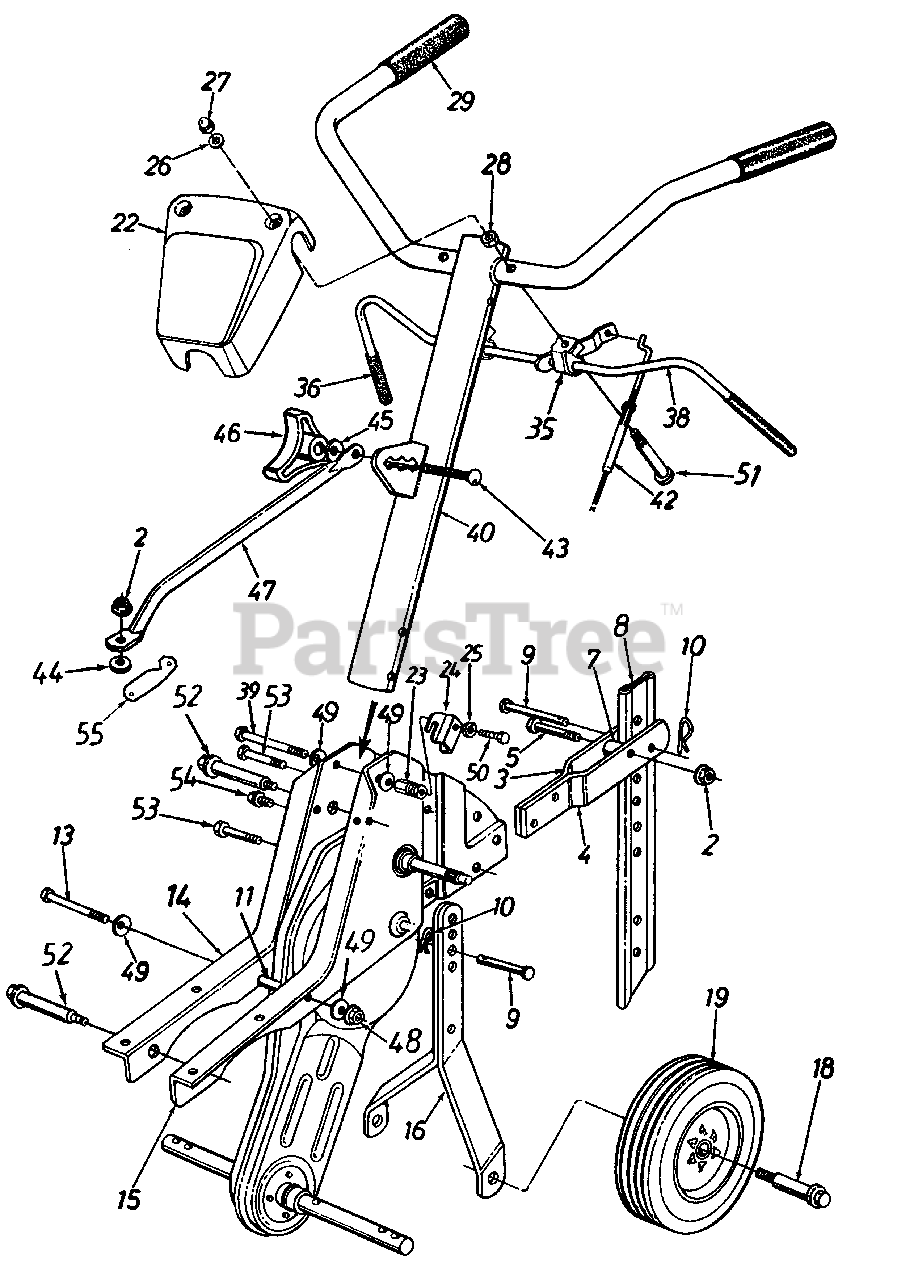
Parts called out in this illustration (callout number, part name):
2	Hex Flange L-Nut 5/16-18 Thd. (Gr. 5)
5	Hex Bolt 5/16-18 x 1.5" Lg.
7	Spacer .32" I.D. x .75" O.D.
9	Clevis Pin .375" I.D. x 1.62" Lg.
10	Internal Cotter Pin
11	Spacer .326" I.D. x .47" O.D.
13	Hex Bolt 5/16-18 x 2.75" Lg.
18	Shld. Bolt .498" Dia. x 1.45" Lg.
19	Wheel Ass'y.
22	Handle Cover
23	Spec. Hex Nut
25	L-Wash. 5/16" I.D.
26	Fl-Wash. .266" I.D. x .625" O.D.
27	Hex L-Stop Nut 1/4-20 Thd.
28	Hex Nut 1/4-20 Thd.
29	Grip-Handle
35	Clutch Handle Holder
36	Grip-Clutch
39	Hex Bolt 5/16-18 x 3" Lg.
43	Carr. Bolt 5/16-18 x 1" Lg. (Special)
46	Hand Knob
49	Bell-Wash. .345" I.D. x .88" O.D.
50	Hex Bolt 5/16-18 x .75" Lg. (Gr. 5)
51	Hex Bolt 1/4-20 x 2.25" Lg.
52	Shld. Bolt
53	Hex Wash. Hd. TT-Tap Scr. 5/16-18 x .62" Lg.
54	Hex Wash. Hd. TT-Tap Scr. 5/16-18 x 1" Lg.
55	Engine Brkt.
